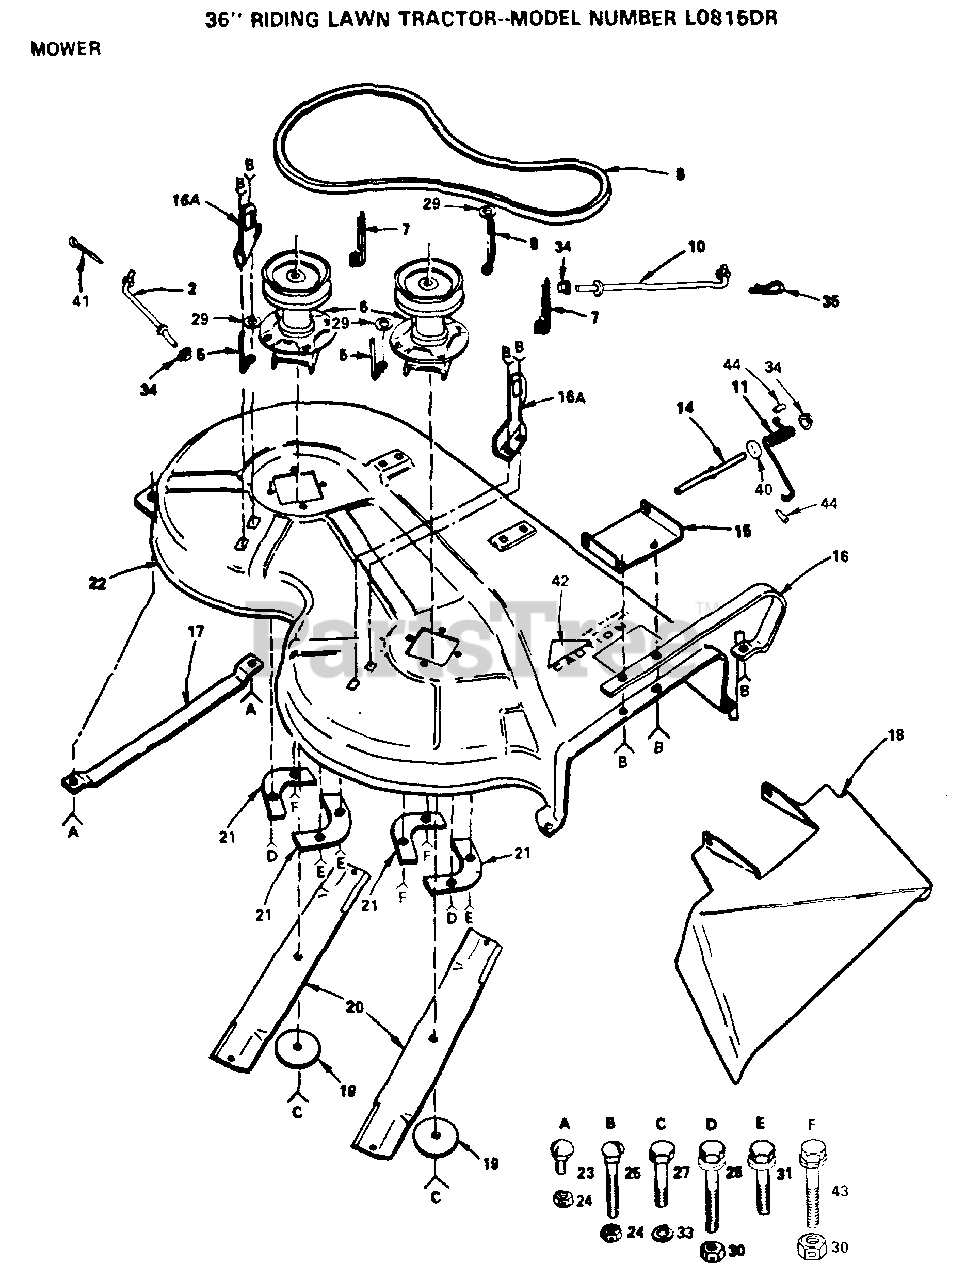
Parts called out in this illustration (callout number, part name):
2	BRAKE ROD LT
5	BELT SNUBBER T
7	BRAKE.ASSY.LT.
9	BELT SNUBBER T
10	BRAKE ROD LT
11	SPRING LT
14	HINGE ROD LT
16A	BRACKET.LIFT
17	SKID LH T
19	WASHER T
21	SUPPORT PLATE LT
23	BOLT
25	BOLT
27	BOLT.3/8-24X1-1/2
28	SCREW
29	WASHER
31	SCREW
33	LOCKWASHER
35	SPRING.RETAINER
40	WASHER
41	COTTER PIN
43	SCREW LT
44	CAP-SLEEVE LT
